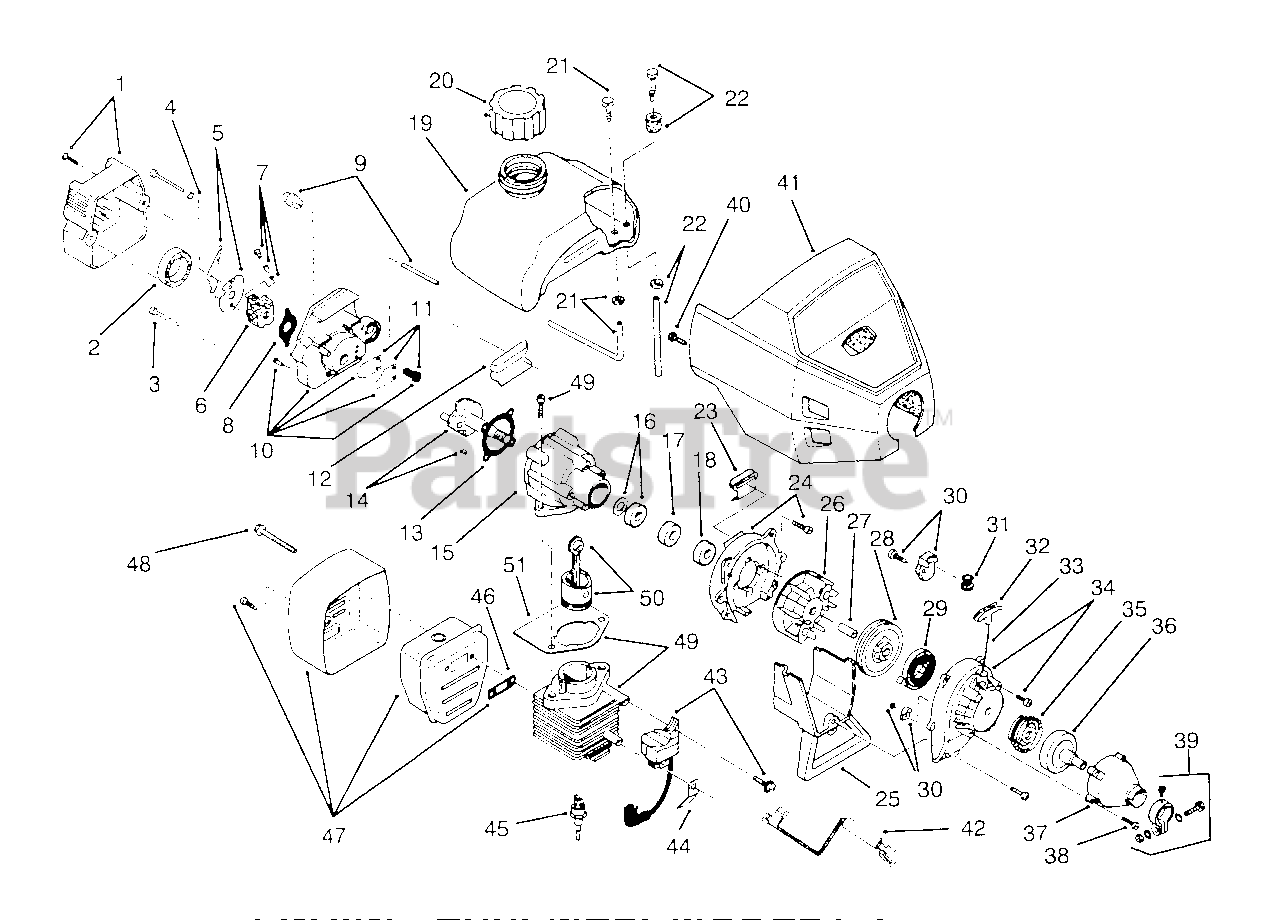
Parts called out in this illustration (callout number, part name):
1	Assy.-Carburetor/Air Clean.(Inc. Ref. No. 2)
2	Filter-Air Cleaner
3	Screw-Carburetor
4	Washer-Wave
5	Choke-Lever and Plate
6	Assembly-Carburetor
7	Throttle Adj.-Walbro
8	Gasket-Carb. (10 Pack)
9	Assy.-Primer and Hose
10	Assembly-Carb. Mount (Incl. Ref. No. 11 & 13)
11	Assembly-Reed
12	Pad-Mounting, Rear
13	Gasket (10 Pack)
14	Assembly-Power Shaft
15	Assy.-Crankcase (Incl. Ref. No. 14-18)
16	Assembly-Inner Bearing
18	Assembly-Outer Bearing
19	Assemby-FuelTank (Incl. Ref. No. 20-22)
20	Assembly-Fuel Cap
21	Assembly-Return Line
22	Assembly-Fuel Line
23	Pad-Mounting, Front
24	Assembly-Shroud
25	Shroud Extension & Stand
26	Assembly-Flywheel
28	Assembly-Recoil Pulley
29	Spring-Recoil
30	Assembly-Pulley Retainer
31	Guide-Rope
32	Handle-Pull
34	Assembly-Starter Housing
35	Assembly-Clutch Rotor
36	Assembly-Clutch Drum
37	Assembly-Clutch Cover
38	Screw-Clutch Cover
39	Assembly-Clamp
40	Screws-Engine Cover
41	Assembly-Engine Cover
42	Assembly-Lead Wire
43	Assembly-Module
44	Tab-Ground
45	Spark Plug
46	Gasket-Exhaust (10 Pack)
47	Assembly-Muffler
48	Bolt-Muffler
49	Assembly-Cylinder (Incl. Ref. No. 51)
50	Assy. Piston & Rod
51	Gasket-Cylinder
